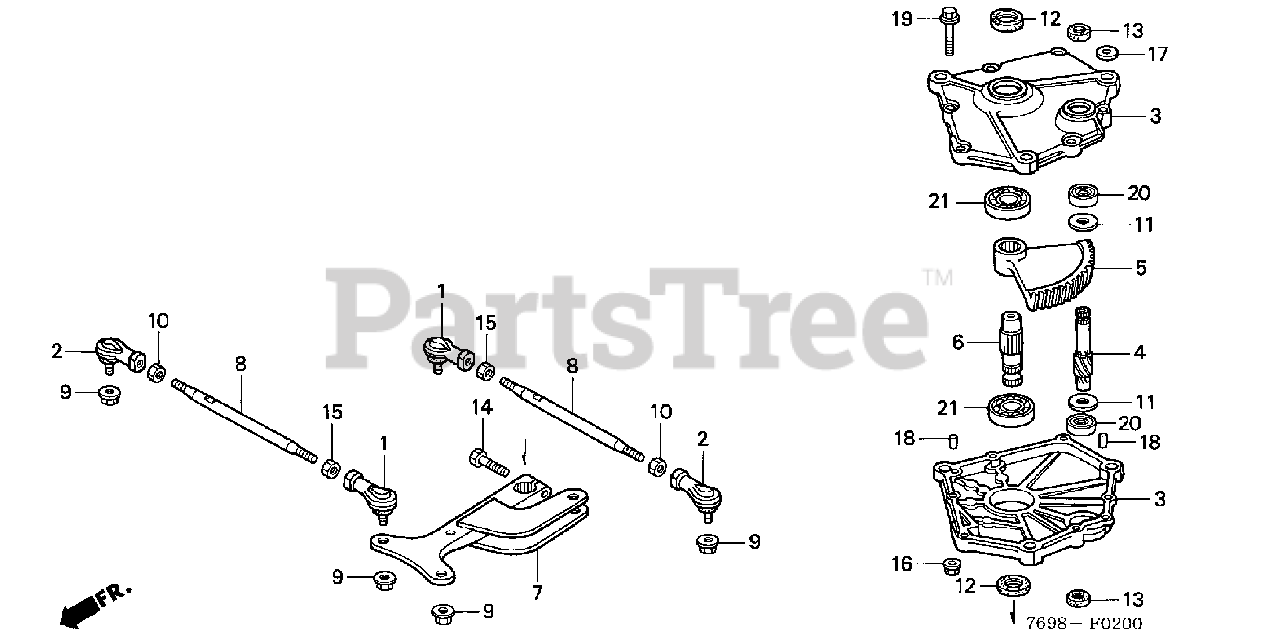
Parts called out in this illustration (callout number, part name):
1	JOINT, R. BALL (ER10)
2	JOINT, L. BALL (ER10)
3	CASE, STEERING GEAR
4	PINION, STEERING
5	GEAR, STEERING
6	SHAFT, STEERING SECTOR
7	ARM, PITMAN
8	TIE ROD, FR.
9	NUT, SELF-LOCK (10MM)
10	NUT, L. HEX. (10MM)
11	WASHER, THRUST (15X1)
12	DUST SEAL (37X25X6)
13	DUST SEAL, CONNECTING ROD PIVOT
14	BOLT, HEX. (10X40)
15	NUT, HEX. (10MM)
16	NUT, FLANGE (6MM)
17	WASHER, PLAIN (10MM)
18	PIN, DOWEL (5X8)
19	BOLT, FLANGE (6X40)
20	BEARING, RADIAL BALL (6202)
21	BEARING, RADIAL BALL (6205)
